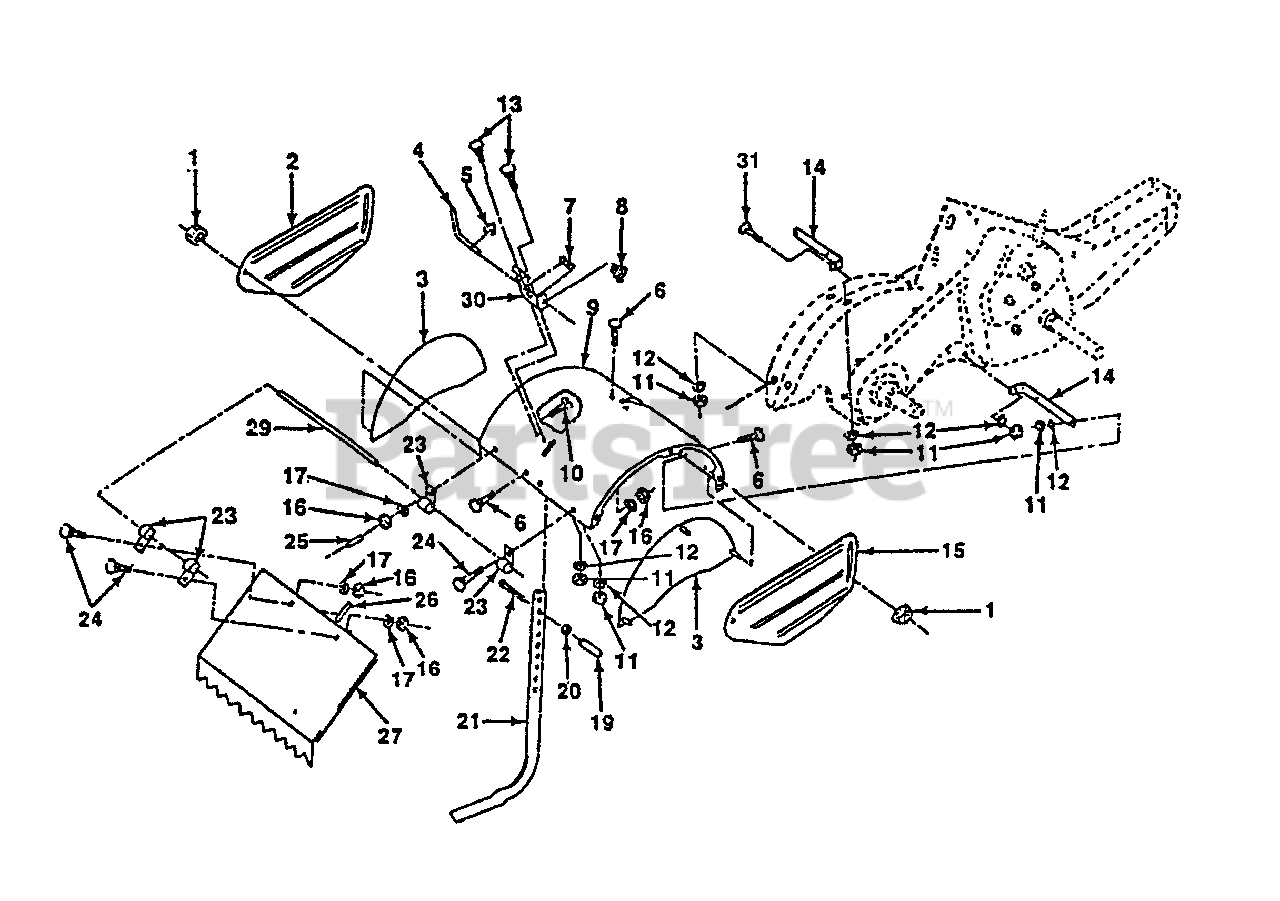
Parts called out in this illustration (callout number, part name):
1	Nut, Flange 5/16-18
2	Shield, Side outer L.H.
3	Shield, Side
4	Pin, Stake Depth
5	Ring, Klip
6	Bolt, Carriage 5/16-18 x 3/4 Gr 5
8	Spring, Depth Stake
9	Shield, Tine
10	Bolt, Carriage 1/4-20 x 1-1/4 Gr. 5
11	Nut, Hex 5/16-18
12	Washer, Lock 5/16
13	Bolt, Carriage 5/16-18 x 1
14	Bracket, Shield Tine
15	Shield, Side Outer R.H.
16	Nut, Hex 1/4-20
17	Washer, Lock 1/4
20	Nut, Hex 3/8-16
21	Stake, Depth
22	Bolt, Hex 3/8-16 x 2
24	Bolt, Carriage 1/4-20 x 1/2 Gr. 5
25	Cap, Vinyl
26	Pad, Idler
27	Shield, Leveling
29	Pin, Hinge
30	Bracket, Latch
31	Bolt, Carriage 5/16-18 x 1-1/4
